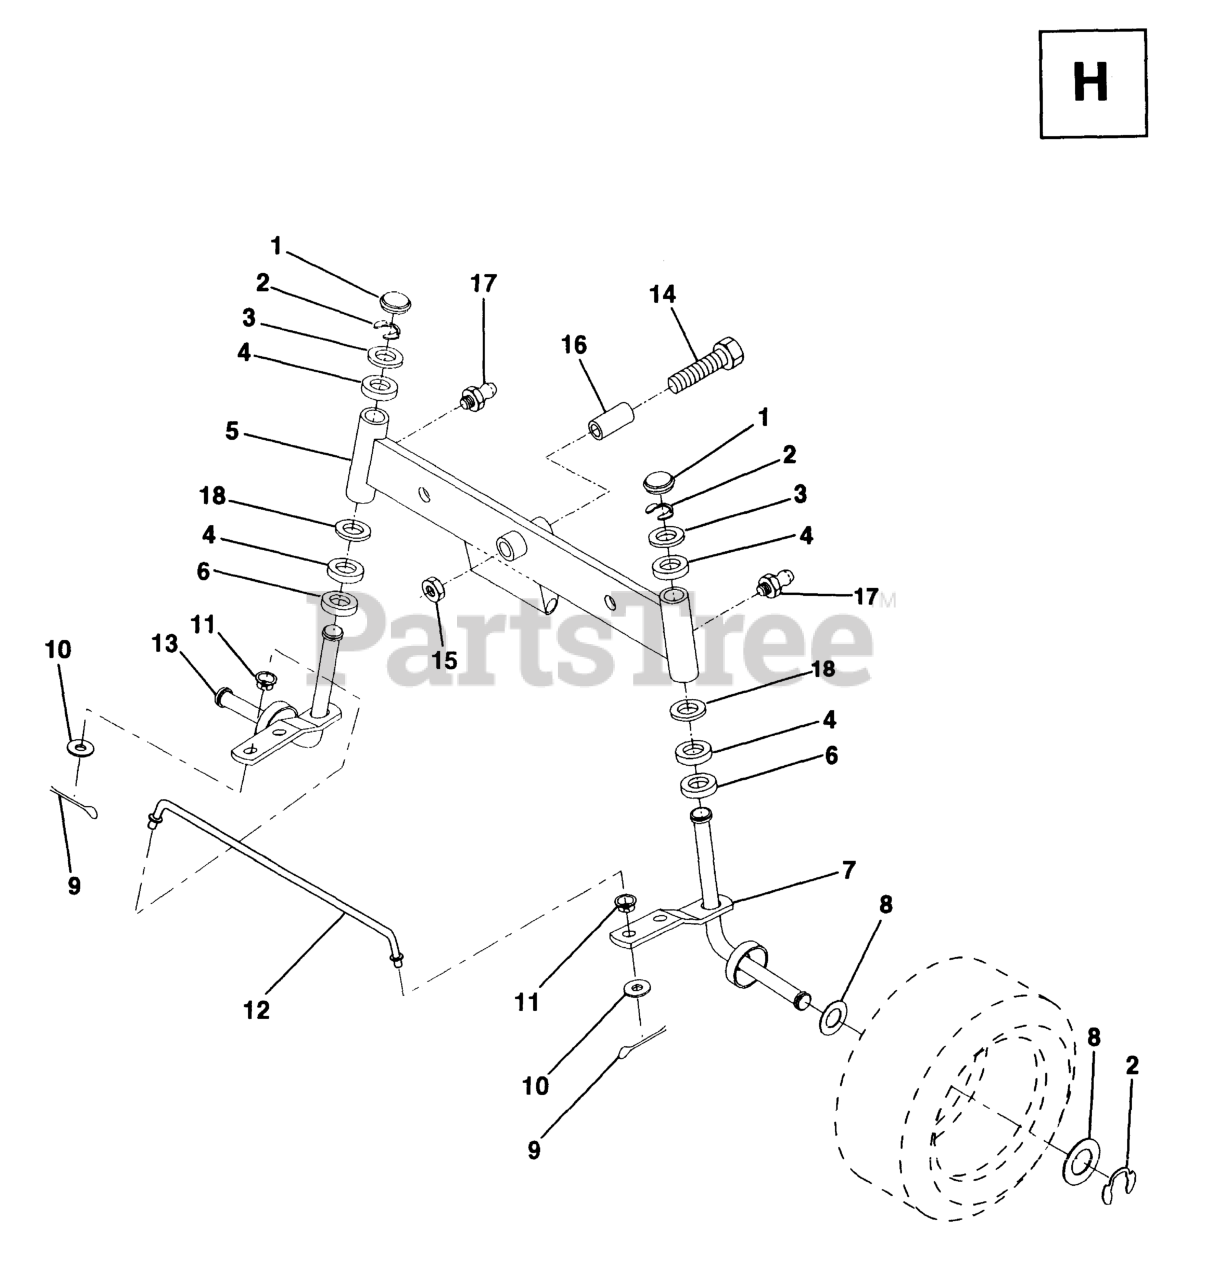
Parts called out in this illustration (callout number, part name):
1	CAP.SPINDLE.BLACK
4	BRNG T
5	AXLE
6	THRUST WASHER
7	SPINDLE ASSY RH NLA
9	COTTER PIN
10	WASHER
11	BUSHING.DRAGLINK (2 2)
12	TIE ROD
13	SPINDLE ASSY LH
14	Bolt, Hex Head 5/8-11 x 3-1/2
15	NUT-LOC,FLANGE LT
17	ZERK M
